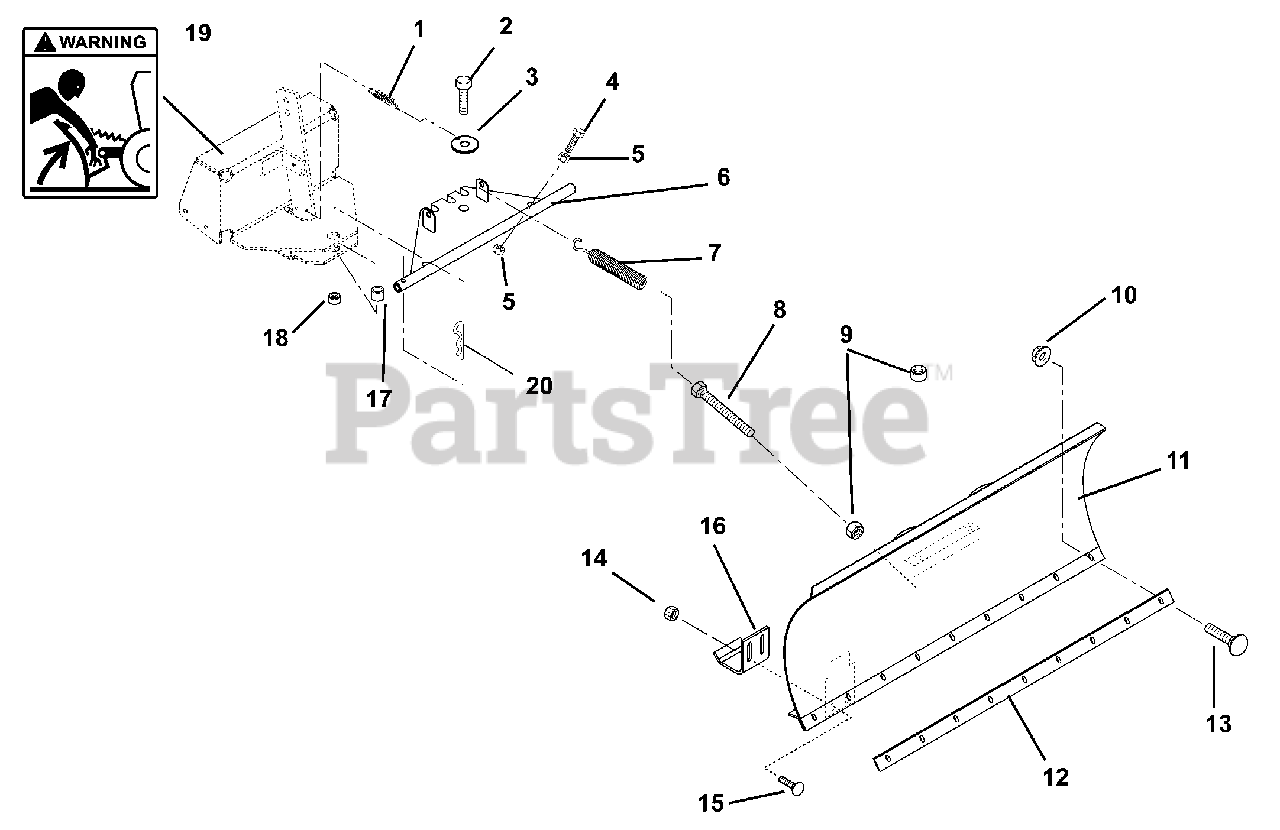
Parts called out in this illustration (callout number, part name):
1	Spring, Latch
2	Bolt, Hex .75-10 x 3.00 Grade 5
3	Washer, .38 Special
4	Bolt, Hex .50-13 x 2.00 Grade 5
5	Nut, Hex .50-13
6	Weldment, Pivot Plate
7	Spring, Blade Adjustment
8	Bolt, Hex .38-16 x 4.00 Full Thread
9	Nut, Hex .38-16
10	Nut, Locking-Top Flange .31-18
11	Weldment, 54" Blade
12	Plate, Wear
13	Bolt, Round Head Square Neck .31-18 x .75 Grade 5
14	Nut, Hex .38-16
15	Bolt, Round Head Square Neck, 3/8-16 x 1 Grade 5
16	Skid Shoes
17	Spacer .753 x 1.00 x 1.60
18	Nut, Locking-Jam-Nylon .75-10
19	Decal, Pinch Point
20	Internal Hair Pin, .15 x 2.937
